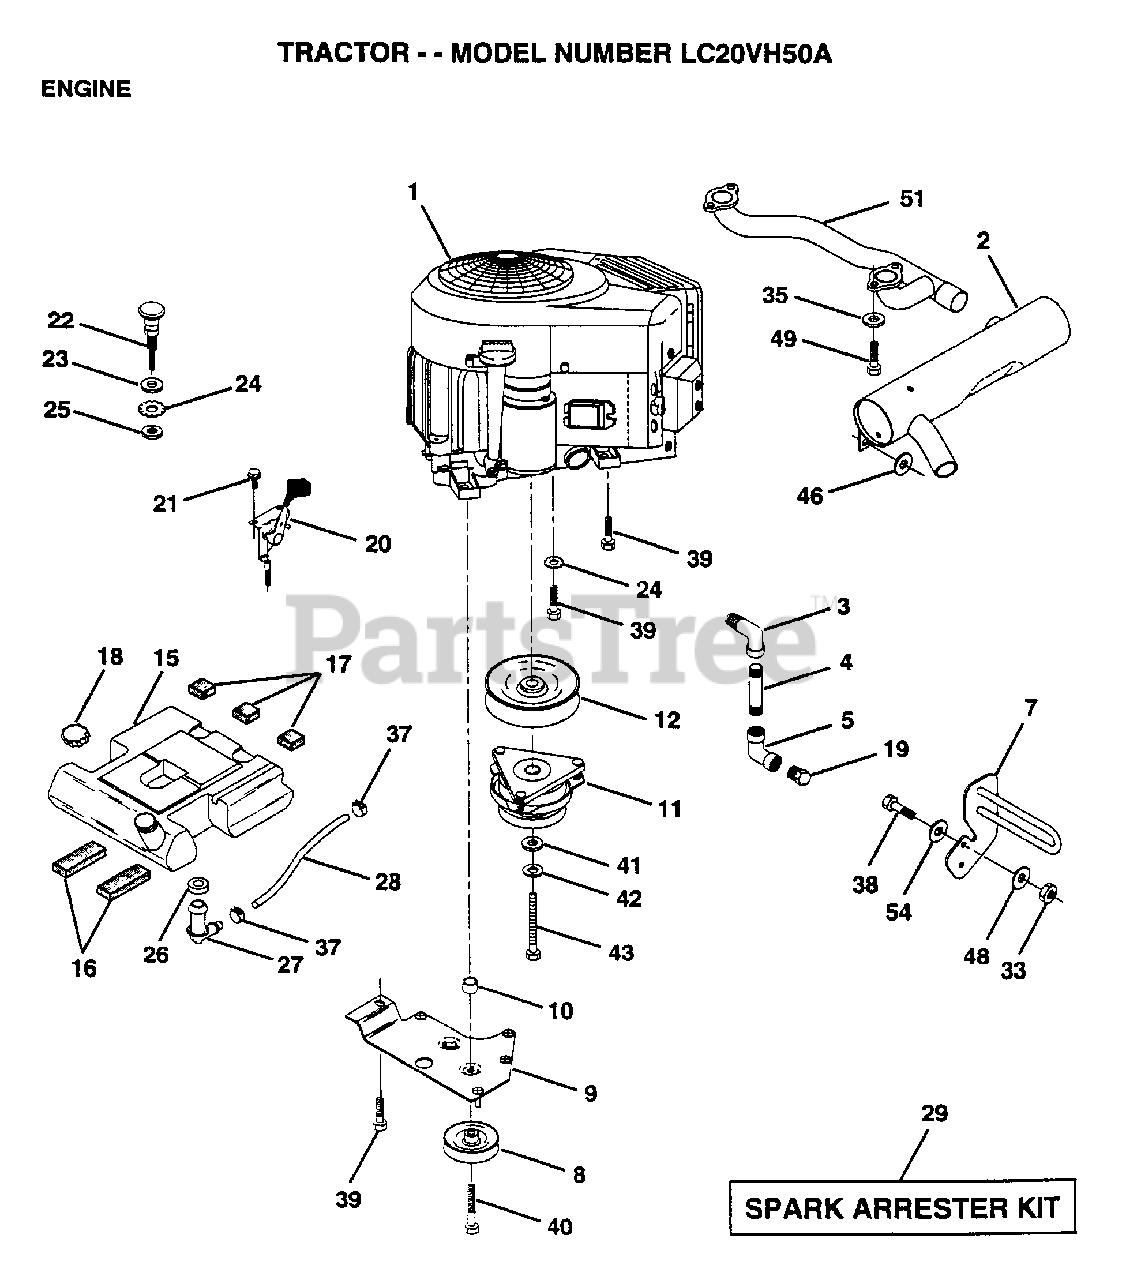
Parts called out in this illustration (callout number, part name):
3	STREET ELBOW LT
4	PIPE NIPPLE
5	ELBOW
10	BUSHING.
12	PULLEY.ENGINE.VGT
16	PAD IDLER TI
17	PAD-SPACER LT
18	CAP ASM FUEL
19	PLUG T
20	CONTROL.THT.FLG.
21	SCREW LT
22	CHOKE CONTROL
23	WASHER
24	LOCKWASHER
26	BUSHING OUTLET T
27	STEM.TANK.FUEL
29	SPARK ARREST KIT
33	NUT
35	LOCKWASHER
37	HOSE CLAMP
38	"BOLT,HEX"
39	SCREW LT
40	SCREW.3/8-16X3.25
41	WASHER
42	LOCKWASHER
46	WASHER HYT
48	WASHER T
49	BOLT.HD.SOCKET.
51	PIPE.EXHAUST.B&S
54	WASHER
